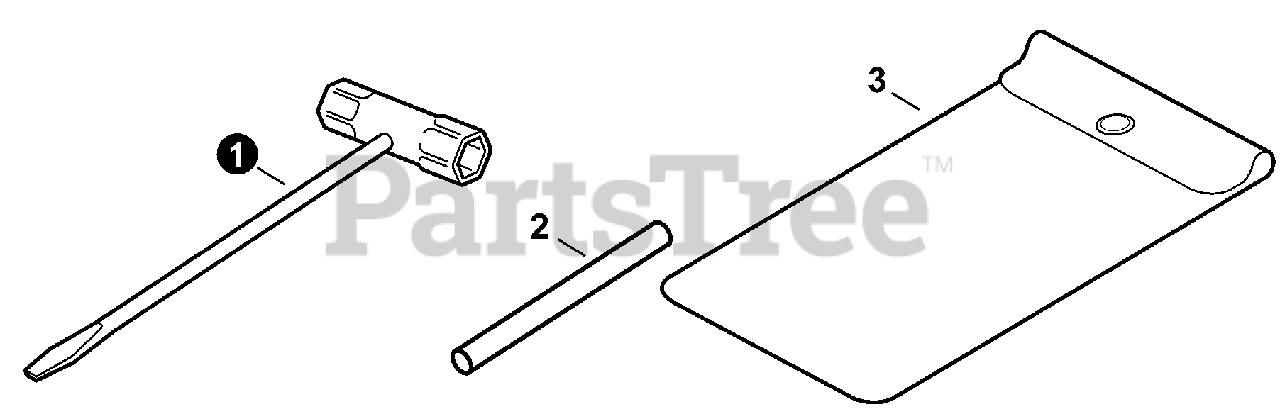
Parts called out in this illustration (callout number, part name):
1	T-WRENCH 17×19 L200
2	TOOL, LOCKING 5×120mm
3	BAG, TOOL
